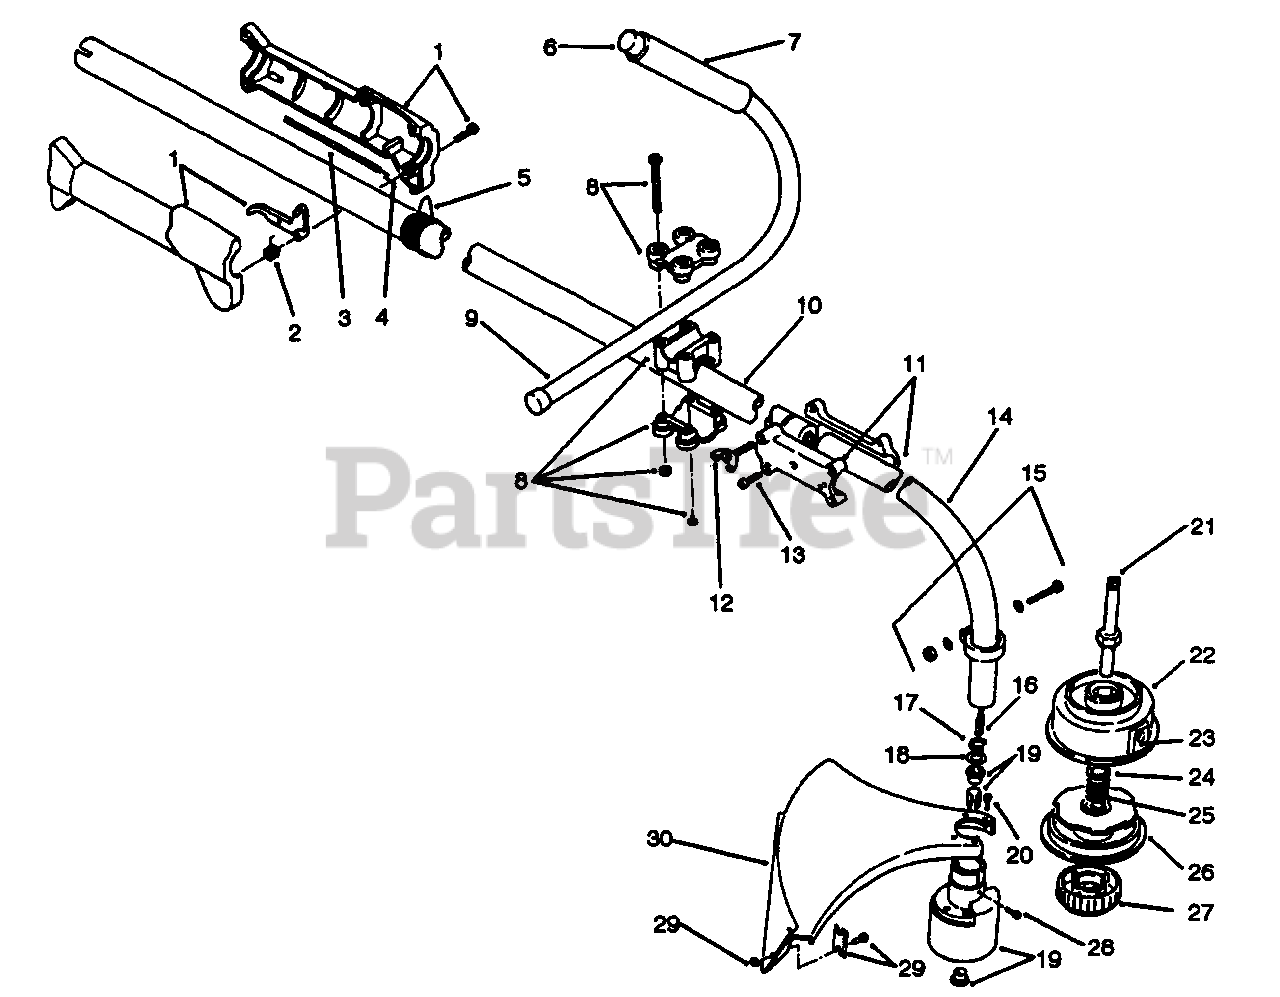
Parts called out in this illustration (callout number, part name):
1	Assy.-Throttle & Trigger (Incl. 6 Screws)
2	Spring-Throttle Trigger
3	Housing-Cable, Throttle
4	Cable-Throttle
5	Clip-Shoulder Strap
6	Closure-Tube
8	Assembly-Bracket Handle (Incl. 4 Screws & Nuts)
9	Assembly-J-Handle (Incl. Ref. No. 6 & 7)
10	Assy.-Upper Drive
11	Coupling-Split Boom
12	Assy.-Adjustment Knob
13	Bolt-Coupling
14	Assy.-Lower Drive Shaft
15	Assy.-Lower Clamp
16	Shaft-Flexible Drive
17	Ring-Retaining
19	Assy.-Bushing Housing
20	Assy.-Guard Mount Screw
21	Shaft-Spool
22	Assy.-Outer Spool & Eyelet
24	Retainer (10 Pack)
26	Reel-Inner
27	Assy.-Bump Head
28	Screw-Anit-Rotation
29	Assembly-Blade (Incl. 2 Screws & 2 Nuts)
30	Assy.-Guard & Blade (Incl. Ref. No. 29)
